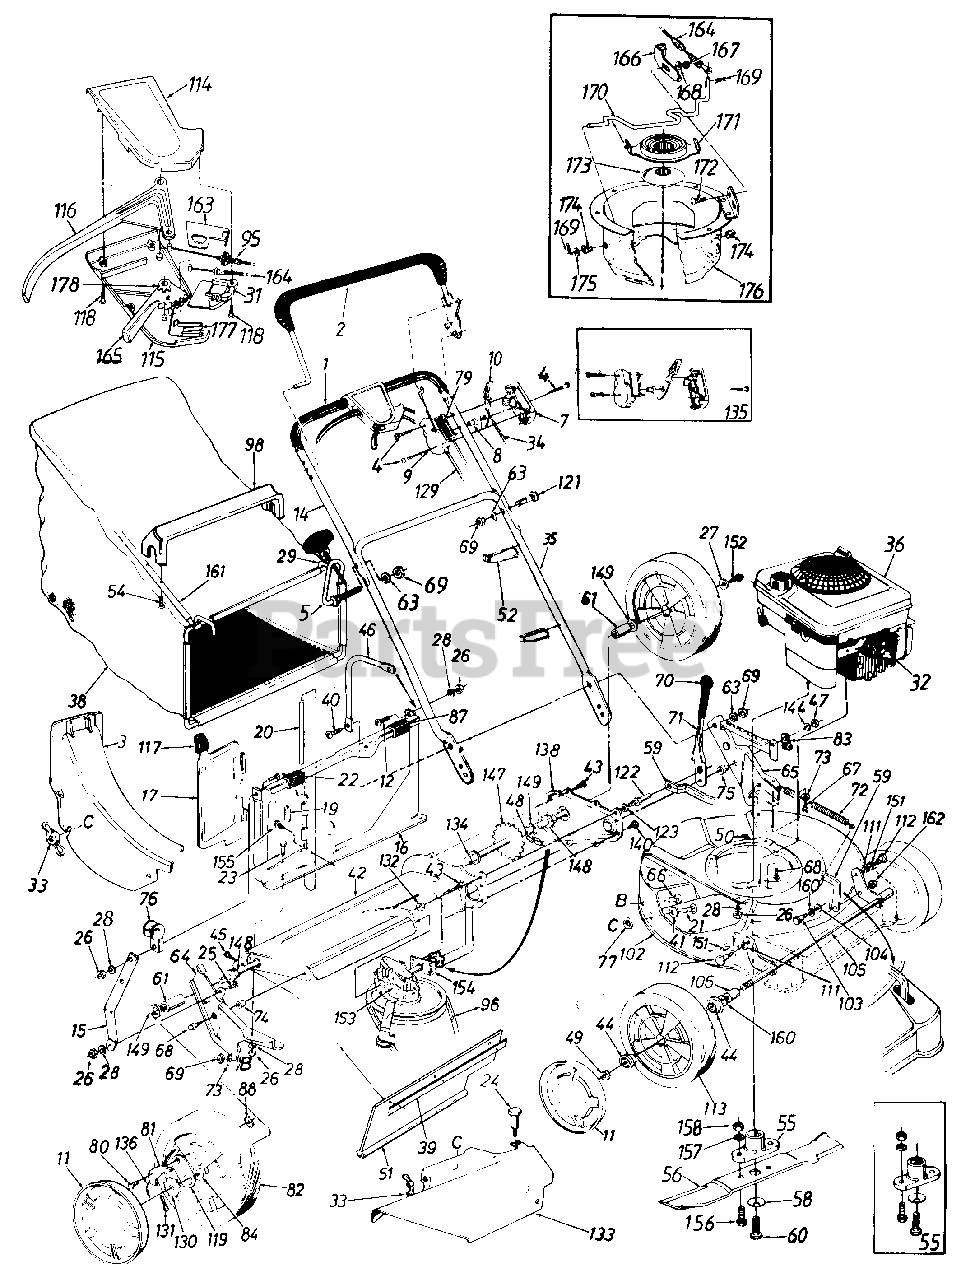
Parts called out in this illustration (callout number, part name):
1	Foam Grip
2	Control Handle Ass'y.-L.H.
3	Rear Discharge Chute Ass'y.
4	Truss Mach. Scr. #12 x 1.50" Lg.
5	Rope Guide Bolt
7	Control Panel Half
8	Control Disc Pin
9	Clutch Panel Half
10	Throttle Control Lever
11	Hub Cap
12	Truss Mach. Scr. 1/4-20 x .62" Lg.
14	Upper Handle-Painted
19	Torsion Spring
20	Pivot Pin
21	Carriage Bolt 1/4-20 x .62"
22	Truss Mach. Scr. 1/4-20 x 3/4" Lg
23	Hex Bolt 1/4-20 x .50" Lg.
24	Shoulder Bolt .312 Dia. x .18 Lg.-Special
25	Hex Bolt 1/4-20 x .62" Lg.
26	Hex Nut 1/4-20 Thd.
27	Bell-Wash. 1/4" I.D.
28	L-Wash. 1/4" I.D.
31	S.P. Control Cover
32	Spark Plug Insulator
33	Wing Nut w/Washer
34	Throttle Control Wire 61"
35	Lower Handle-Painted
36	Engine
38	Grass Bag
39	Retaining Strip
40	Truss Mach. Scr. 5/16-18 x .75" Lg.
41	Fl-Wash. .344" I.D. x .62"
44	Flange Ball Bearing 1/2" I.D.
45	Hex AB-Tap Scr. 1/4 x .62"
46	Catcher Panel Support Arm
47	Hex Patch L-Nut 3/8-24 Thd.
48	#48 Chain .500" Pitch x 30 Links
49	Hex L-Nut 1/2-20 Thd.
51	Rear Flap 3.75" x 17.30" Lg.
52	Cable Tie
54	Hex AB Scr. #12 x 1.25" Lg.
55	Blade Adapter Kit
56	21" Blade
58	Bell-Wash..46" I.D.
59	Height Adj. Connecting Arm
60	Hex Bolt 7/16-20 x l.5" Lg. (Grade 5)
61	Spacer .513" I.D. x .703" O.D. x .69" Lg.
63	L-Wash. 5/16" I.D.
64	R.H. Handle Wheel Brkt. Ass'y.
65	L.H. Handle Wheel Brkt. Ass'y.
66	Carriage Bolt 5/16-18 x .62"*
67	Hex Wash. Hd. B-Tap Scr. 5/1 6-1 8
68	Hex Wash. Hd. TT-Tap Scr. 3/8-1 6
69	Hex Nut 5/16-18 Thd.
71	Height Adj. Lever
72	Extension Spring .75" O.D. x8" Lg.
73	Bell-Wash. 5/16" I.D.
74	Spacer
75	Shld. Spacer .500" Dia.
76	Rope Guide
77	Bolt Retainer 1/4 x .50 O.D.
79	Control Label
80	Shld. Scr. .342" Dia. x .268
81	Pawl
82	Wheel Ass'y. Comp.
83	Clamp
84	Bearing 1/2" I.D.
87	Panel Clip
88	Flat Weld Nut 1/4-20 Thd.
95	S.P. Cable
96	"V"-Belt
98	Bag Handle
102	21 " Deck Ass'y.
103	Shld. Bolt .5" Dia. x .295
104	Bell-Wash. .515" I.D. x 1.0" O.D.
105	Front Axle Ass'y.
106	Sleeve .526" I.D. x .690" O.D. x .880" Lg.
111	Intern. L-Wash. 3/8 I.D.
112	Shld. Bolt .575" Dia. x .42
113	Wheel Ass'y. Comp.
114	Self-Propelled Control Cover
115	Self-Propelled Control Cover
116	Control Lever
117	Door Grip
118	Fl-'lC"-Sunk Hd. Tap Scr. #10 x .75" Lg.
119	Pawl Plate
121	Curved Carr. Bolt 5/16-18 x 1.38" Lg.
122	Shld. Pin 3/8-24 x 1.43" Lg.
123	L-Wash. 3/8" I.D.
129	Control Cable 46" Lg.
130	Ratchet Wheel 1.62" O.D.
131	Cotter Pin 1/8" Dia. x 1.00" Lg.
132	Hex Jam Nut 3/8-24 Thd.
133	Side Chute Deflector Ass'y.
134	Hex Flange Bearing
135	Kit-Control Housing Comp.
136	0622B Spring-Nylon
144	Fl-Wash. .385" I.D. x .87"
147	Rear Shaft Ass'y. 21.94" Lg.
148	Hex Flange Bearing .506" I.D. Plastic
149	Fl-Wash. .531" I.D. x .930"
151	Flanged Nyliner Brg.
152	Hex Bolt 1/4-20 x .62" Lg. (Grade 5)
153	Transmission Comp.
155	Hex B-Tap Scr. #10 x .38
156	Hex Scr. 3/8-24 x 1.0n Lg.
157	L-Wash. 3/8" I.D.
158	Hex Nut 3/8-24 Thd.
160	Fl-Wash. .51" I.D. x .751' O.D.
162	Hex Jam Nut 3/8-16 Thd.
163	3 Tooth Rack Gear Insert
164	Spd. Control Cable-50" Lg.
165	6-Spd. Shift Lever
168	Bell-Wash. .265" I.D. x .75" O.D.
169	Cot-Pin 3/32" Dia. x .75" Lg.
170	Shift Rod
171	Movable Pulley Half Ass'y.
172	Carr. Bolt 1/4-20 x .50" Lg.
173	Splined Pulley Half
174	Flanged Bushing
175	Fl-Wash. .328" I.D. x .68" O.D.
176	Cable Mtg. Brkt. Ass'y.
177	Shift Lever Spring
178	3 Tooth Rack Gear Insert
